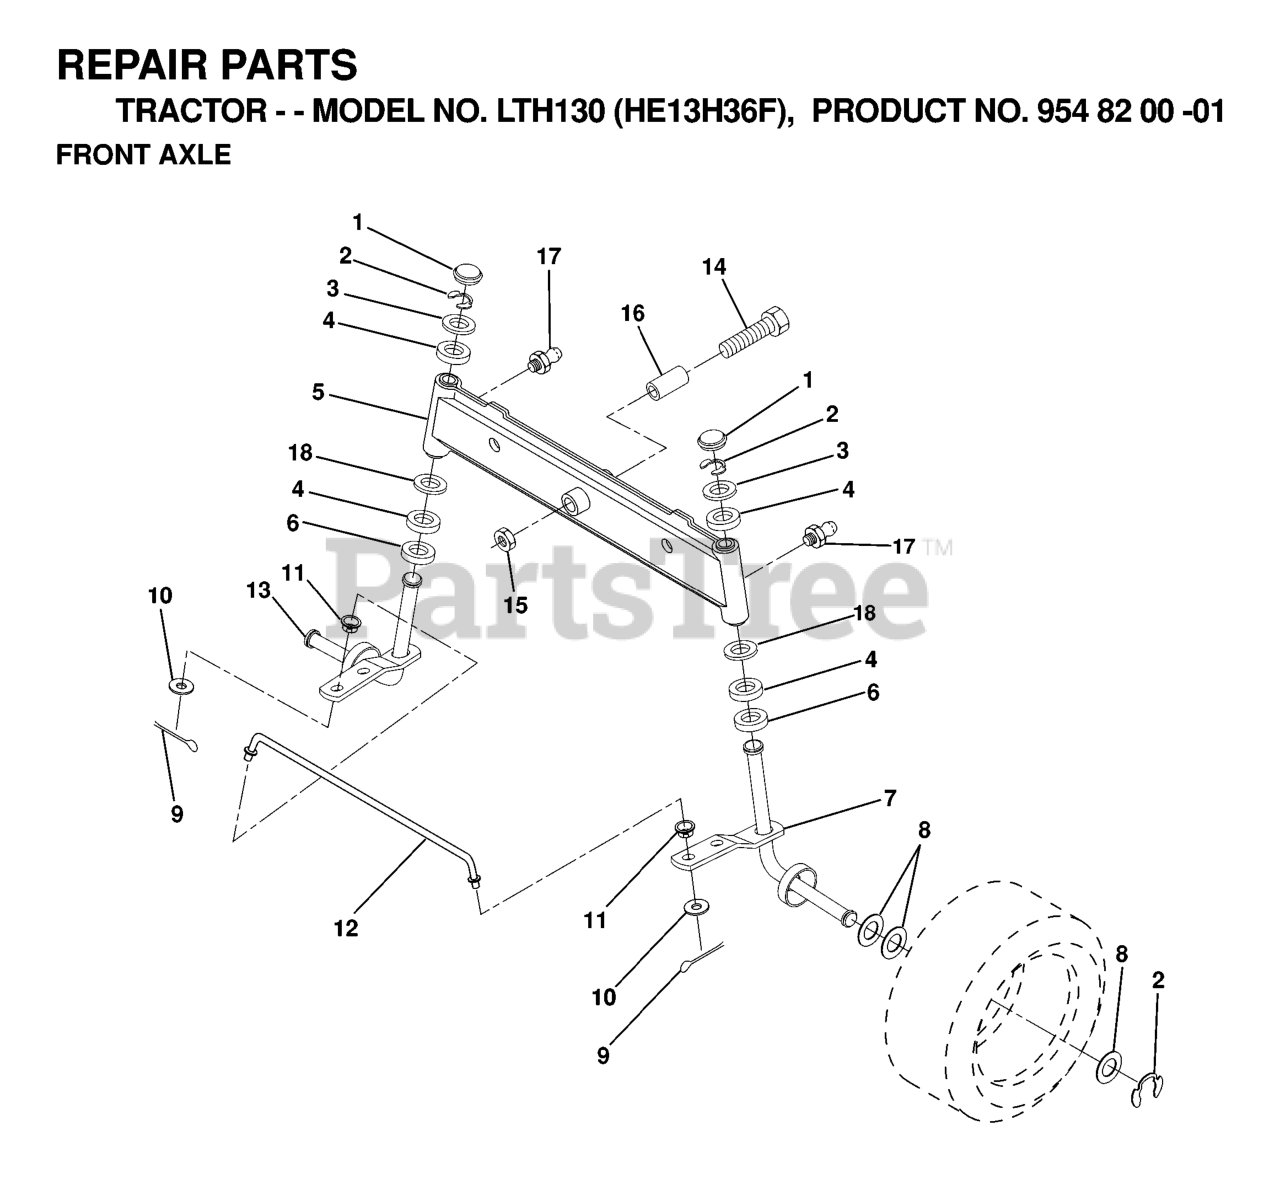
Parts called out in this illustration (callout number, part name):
1	CAP.SPINDLE.BLACK
4	BRNG T
6	THRUST WASHER
9	COTTER PIN
10	WASHER
11	BUSHING.DRAGLINK (2 2)
12	TIE ROD
13	SPINDLE.ASSEM.LH
14	Bolt, Hex Head 5/8-11 x 3-1/2
15	NUT-LOC,FLANGE LT
16	BEARING
17	ZERK M
